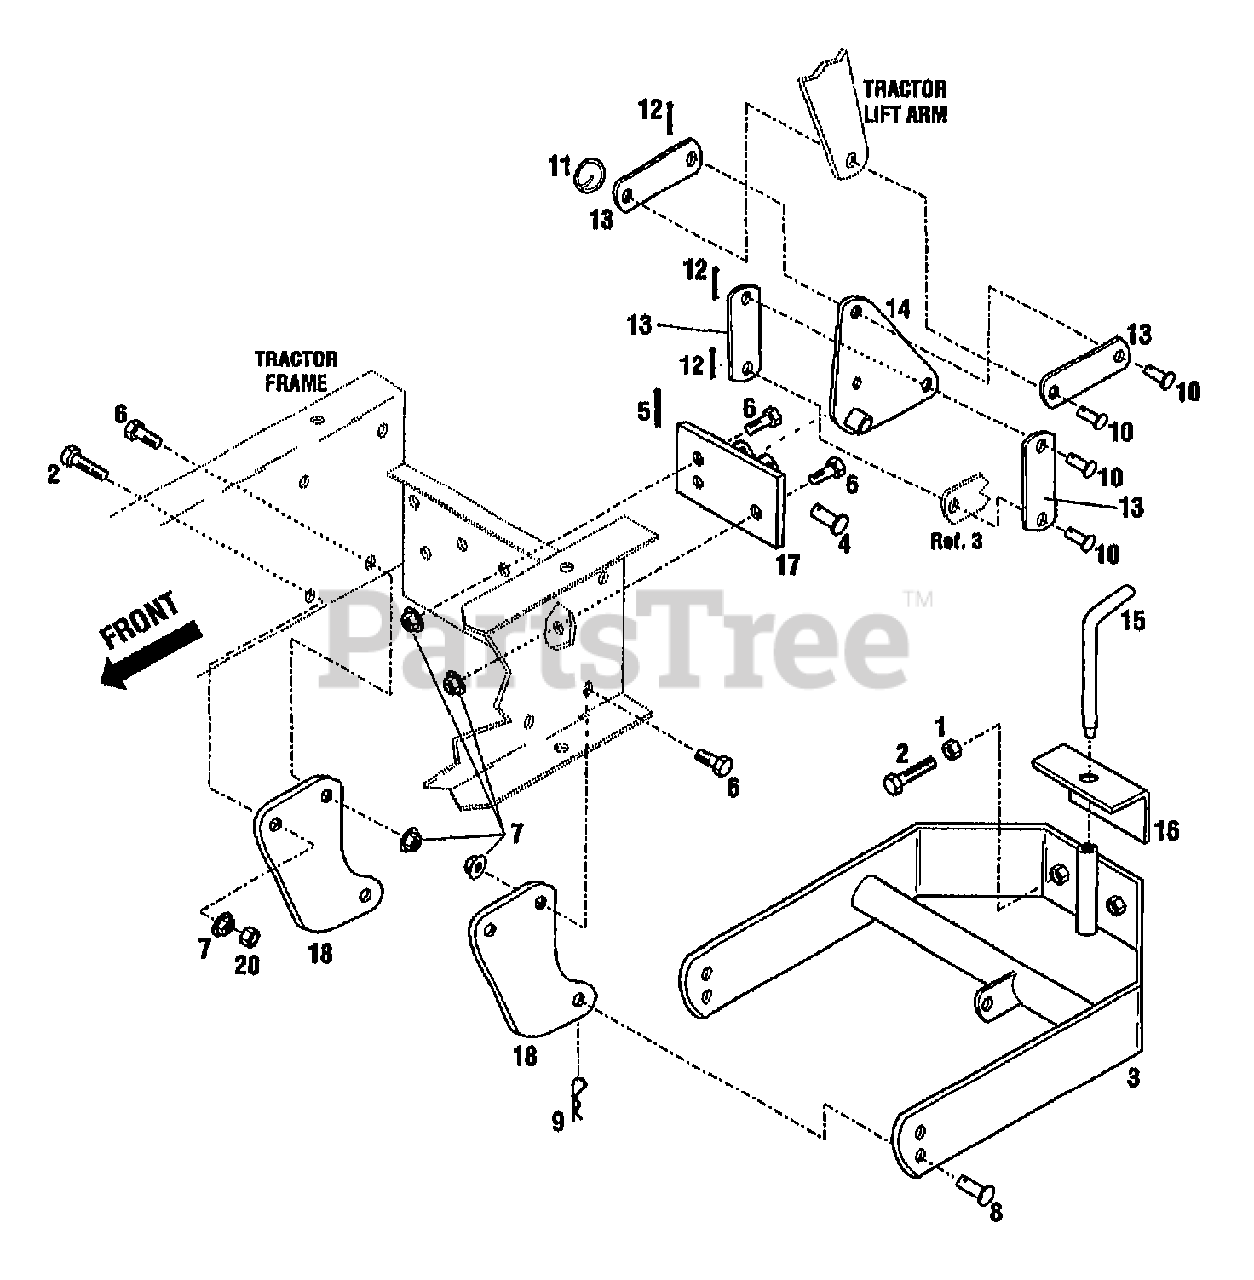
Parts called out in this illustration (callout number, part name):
1	NUT-HEX JAM 1/2-13
2	SCR-HH 1/2-13 X 2.00
4	PIN-CLEVIS .75X2.5
5	PIN-COTTER .120X1.25 ZP
6	SCR-HH 1/2-13X1.0 G5 ZP
7	NUT-TOP LOCK 1/2-13 ZP
8	PIN-CLEVIS
9	PIN-HITCH .125X2.56 ZP
10	PIN-CLEVIS .5X1.25
11	RING-CIRCLE COTTER
12	PIN-COTTER .120X1.00 ZP
15	PIN-HITCH .625 DIA
16	PLATE-STABLIZER
17	ASSM-BRKT MOUNTING HITCH
18	BRKT-HANGER ATTACH
20	NUT-TOP LOCK 1/2-13 ZP
